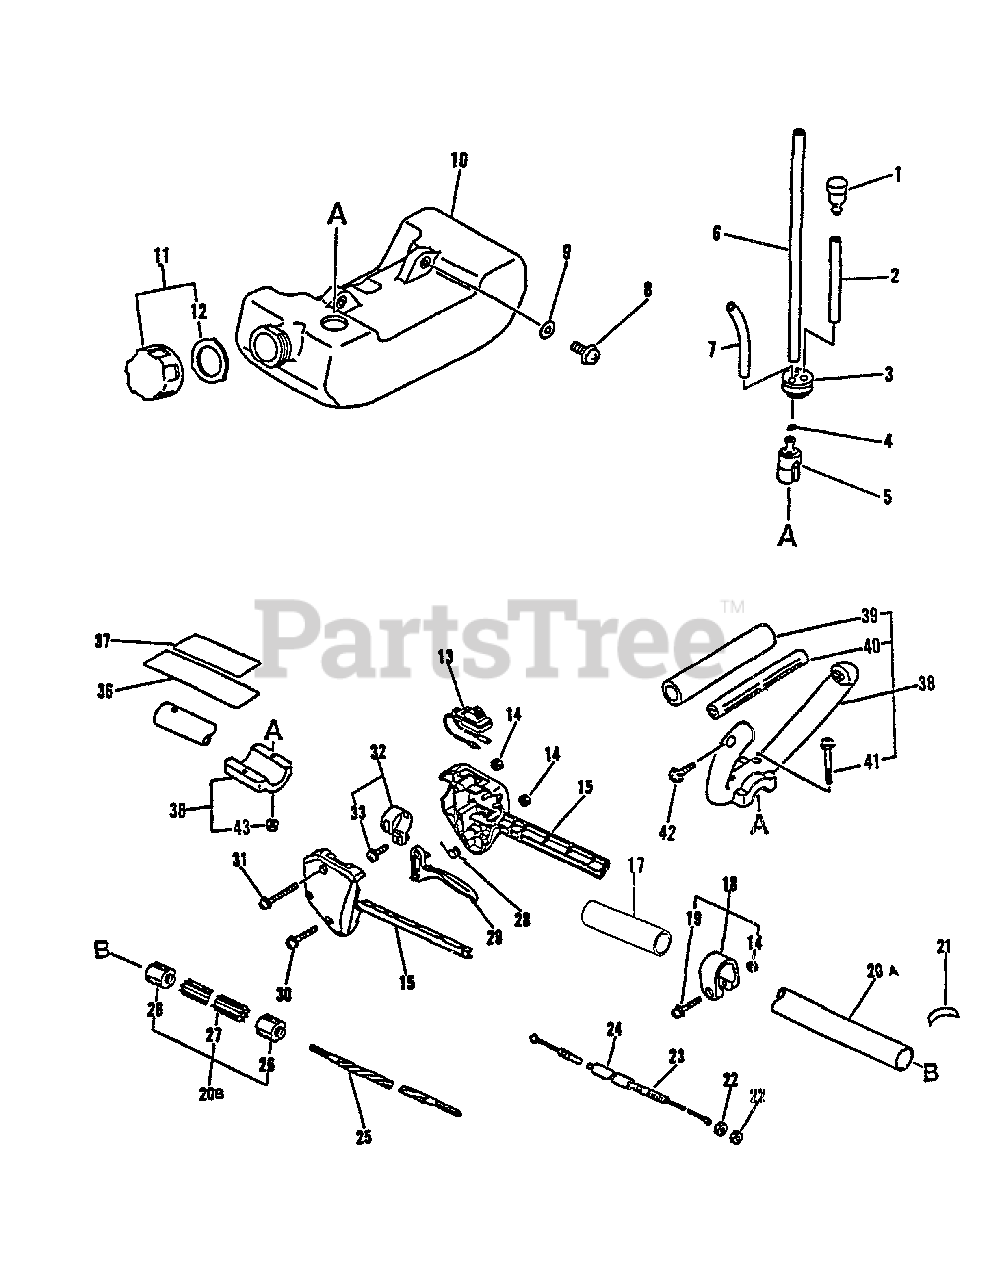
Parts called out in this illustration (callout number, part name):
1	VENT, FUEL TANK
2	PIPE - 3X5X70 -- BLACK
3	GROMMET
4	CLIP - 6
5	FILTER, FUEL
6	PIPE - 3X5X180 -- BLACK
7	PIPE - 3X6X90 -- CLEAR
8	SCREW - 5X16
9	WASHER - 5
10	TANK, FUEL
11	CAP ASSY
12	GASKET, CAP
13	IGNITION SWITCH ASSY
15	CONTROL HANDLE KIT
17	GRIP, HANDLE
18	CLAMP KIT
19	SCREW - 5X28
20	MAIN PIPE ASSY
20A	MAIN PIPE ASSY
20B	MAIN PIPE ASSY
21	LABEL - ALIGNMENT
23	CABLE, THROTTLE
24	TUBE - VINYL
25	DRIVESHAFT - FLEXIBLE
27	LINER - FLEXIBLE
28	SPRING, TRIGGER
29	TRIGGER, THROTTLE
30	SCREW - 5X25
31	SCREW - 5X35
32	CLAMP KIT
33	SCREW - 5X14
34	SCREW - 5X40
35	WASHER - 5
36	LABEL - CAUTION
37	LABEL - CAUTION
38	LOOP HANDLE ASSY
39	GRIP, HANDLE
41	SCREW - 6X35
42	SCREW - 5X30
43	LOCKNUT - 6
